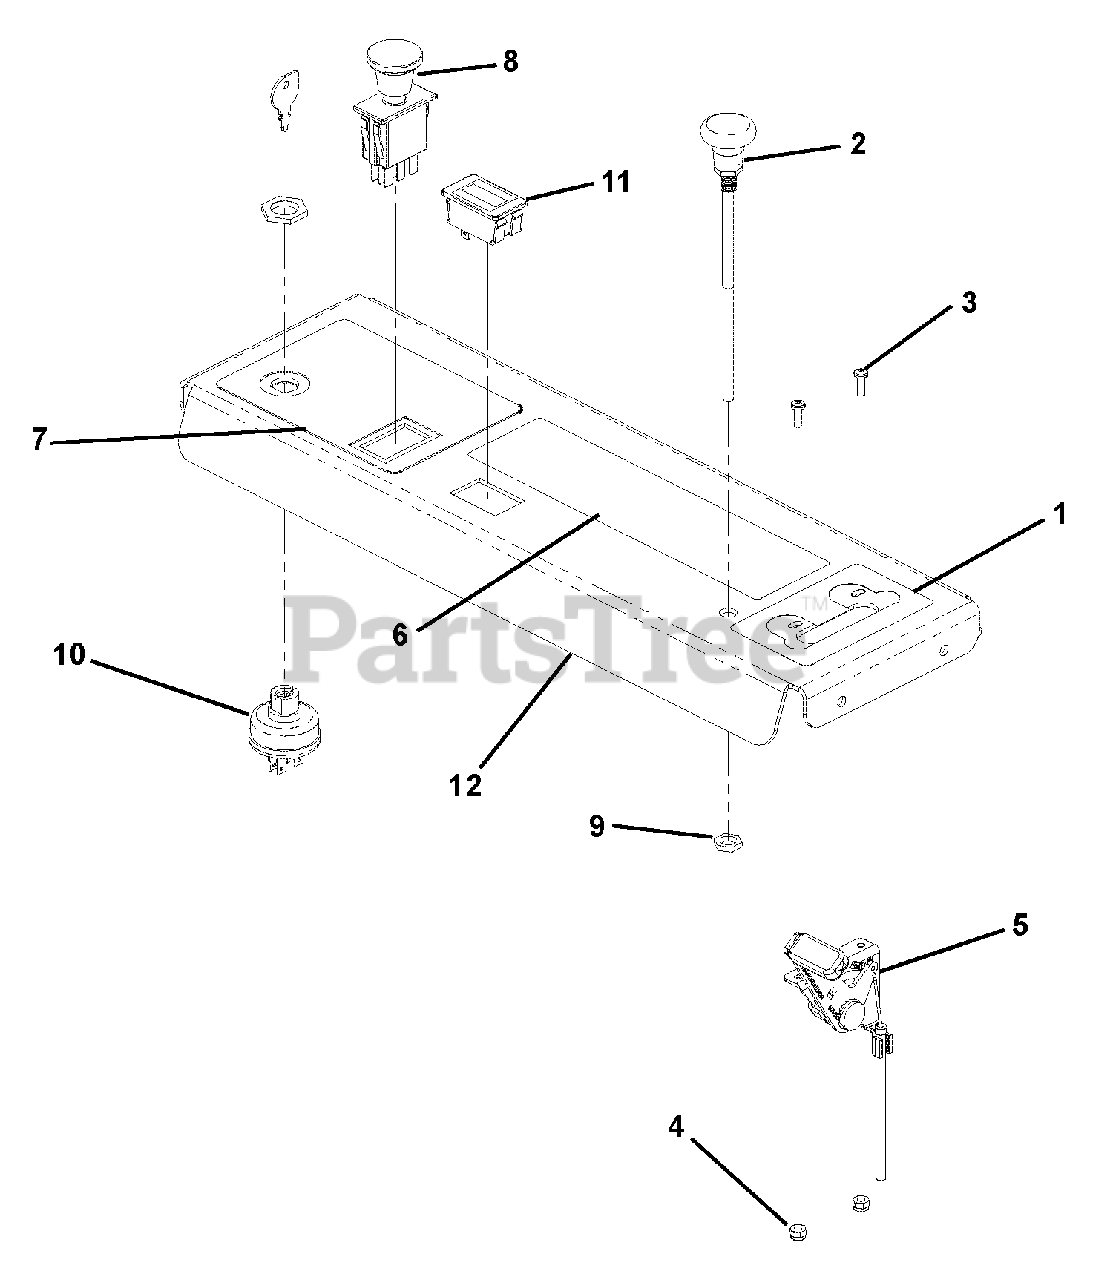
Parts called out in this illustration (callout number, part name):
1	Decal, Throttle
2	Cable, Choke
3	Bolt, Hex 8-32 x .5
4	Nut, Locking, Nylon 8-32 With Insert
5	Cable, Throttle
6	Decal, General Caution
7	Decal, PTO/Ignition
8	Switch, PTO Engagement
9	Nut, Hex .38-16
10	Switch, Key - 3 Position
11	Hour Meter - Digital
12	Assembly, Control Panel
